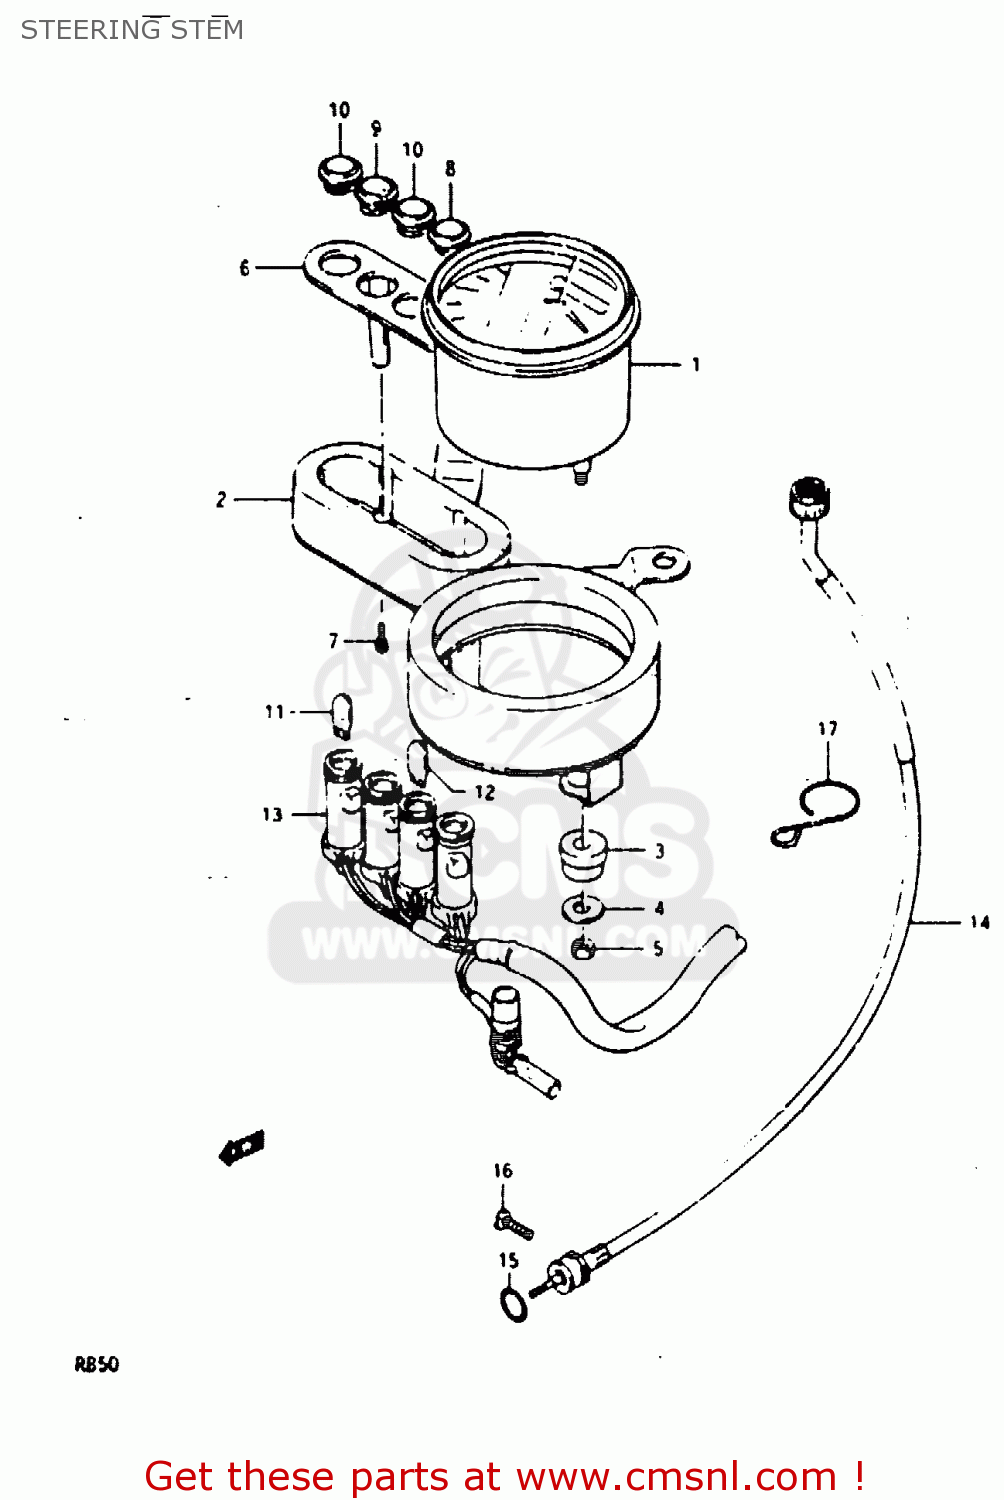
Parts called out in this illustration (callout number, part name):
1	SPEEDOMETER
3	CUSHION
4	WASHER
5	NUT ,5MM
7	SCREW
8	LENS,TURNSIGNAL
9	LENS,NEUTRAL
11	BULB (6V,21W)
12	BULB(6V1.7W,STANLEY,A61A)
14	CABLE ASSY,SPEEDOMETER
15	O RING
16	SCREW
17	GUIDE, SPEEDOMETER CABLE
